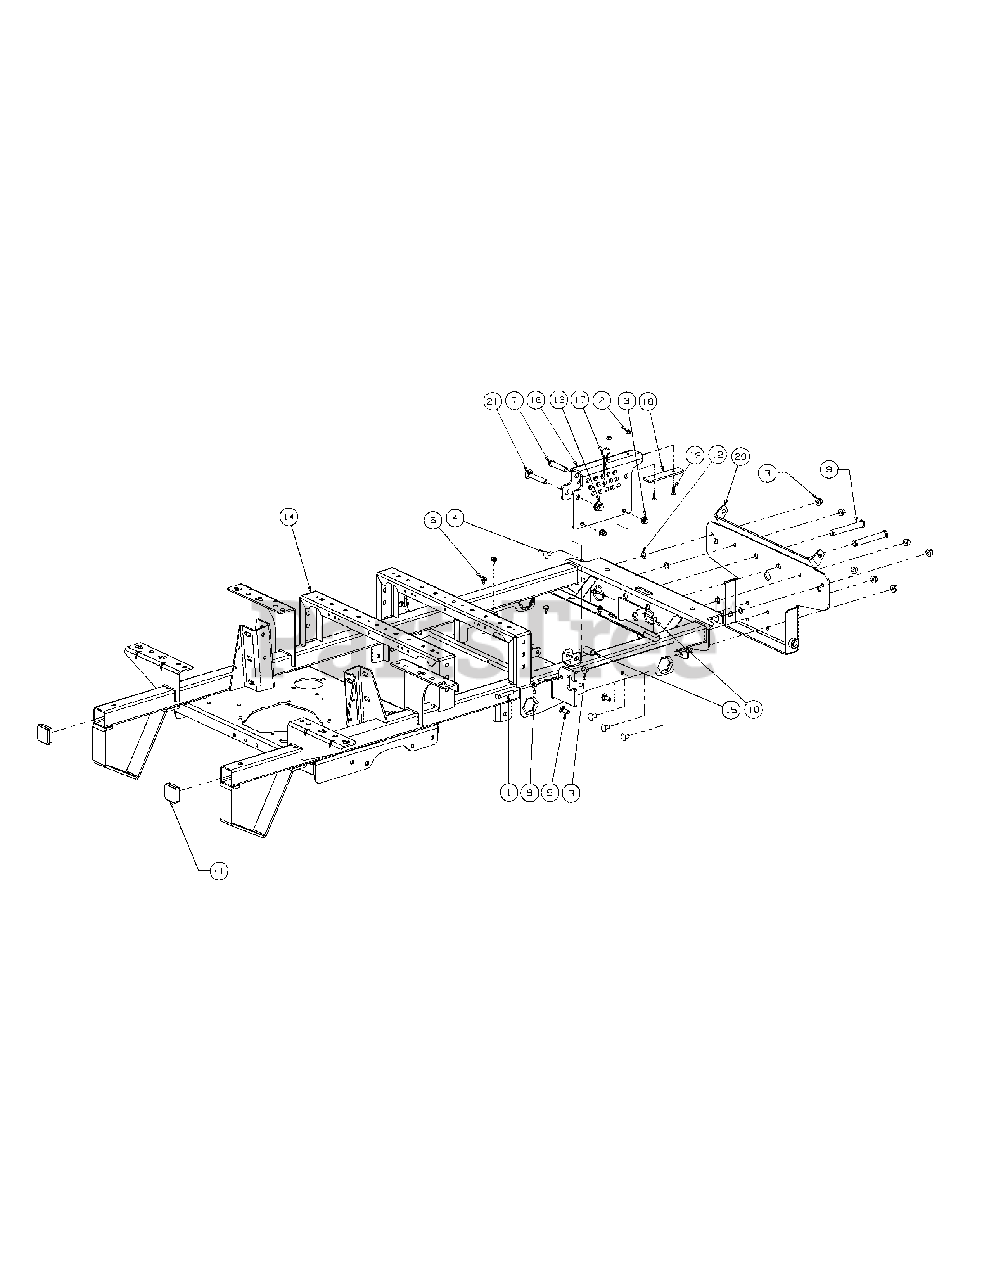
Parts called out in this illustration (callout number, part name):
1	Hex Cap Screw 3/8-16 x 2.00
2	Lock Nut w/Nylon Insert
3	Hex Nut, 3/8-16 Flange Lock
4	Carriage Bolt, 3/8-16 x .75 Long
5	Carriage Bolt, 3/8-16 x 1
6	Rubber Bumper, .62 OD x .22 Thick
7	Clevis Pin, .500 Dia. x 2.50 Lg.
8	Nut, 3/8-16, Jam
9	Clevis Pin, .625 Dia x 4.375 Long
10	Linch Pin, 3/16 Dia.
11	Plug, Square Tube
12	Push Retainer, 3/8
13	Nut, 1/2-13, Flangelock
14	Frame Assembly
15	Spacer, .51 ID x .75 OD x 1.40
16	Lift Index Bracket
17	HitchPin, .120 Dia. x 3.0
18	Wear Plate, 1.25 x 5.00
19	Flat Head Cap Screw, 1/4-20 x .75
20	Bracket Assembly, Frame, Front
21	Carriage Bolt, 1/2-13 x 3.00
